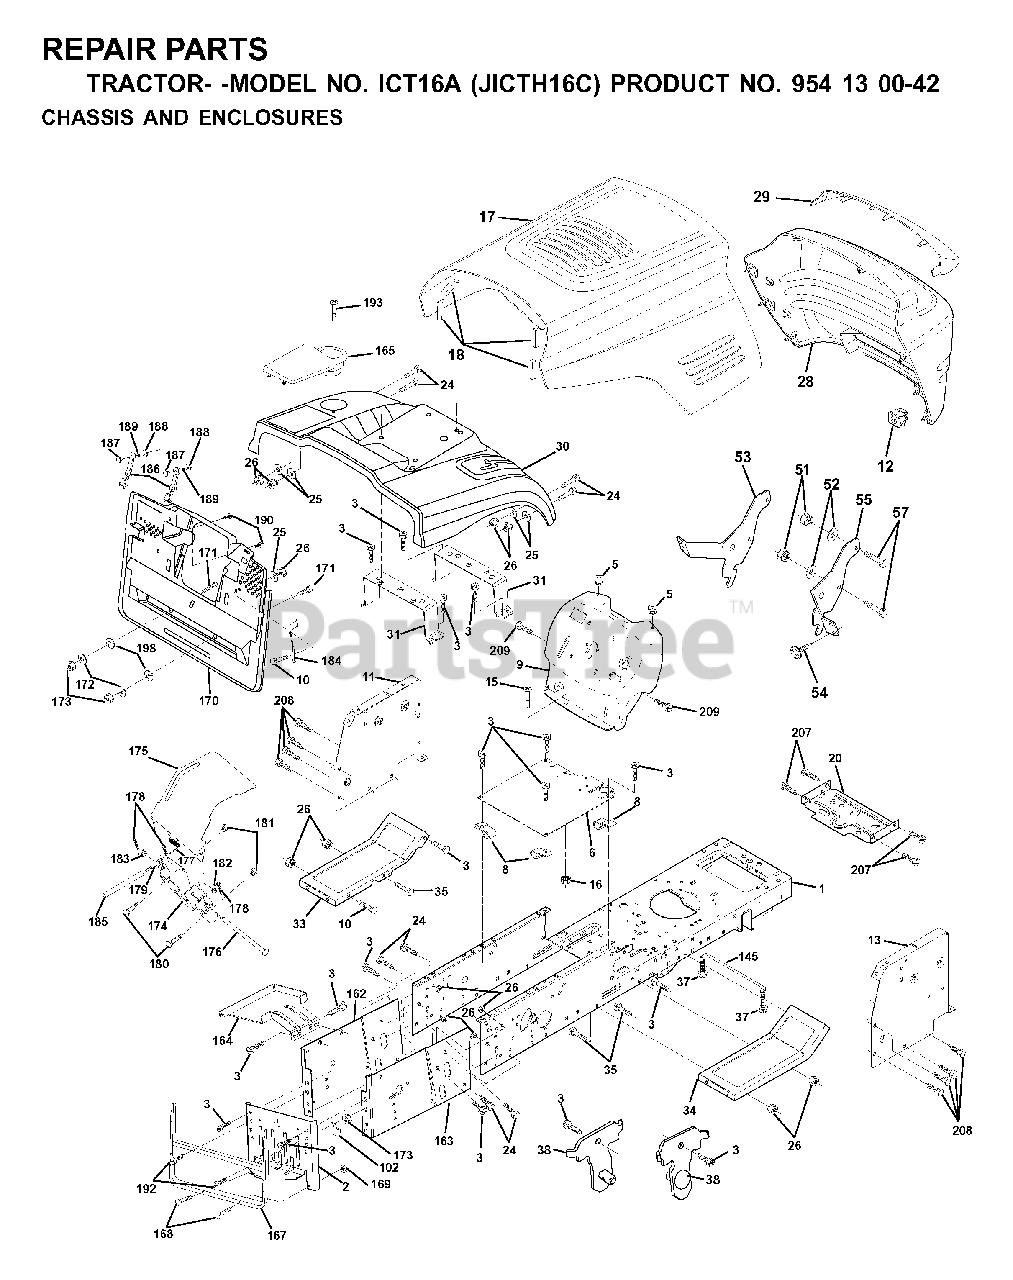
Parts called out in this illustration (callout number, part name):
1	CHASSIS STAMPING
3	SCREW 3/8-16X3/4
5	BUMPER.RUBBER.HOOD
6	SADDLE FLAT
8	CLIP,INSULATOR
10	BOLT D
11	PANEL DASH LH
13	PANEL DASH
16	NUT
18	BUMPER HOOD T
20	PLATE MTG
25	WASHER
26	NUT
31	BRACKET SUPPORT FENDER
38	BRACKET
51	LOCKNUT
57	BOLT
102	CLIP T
145	ROD PIVOT CHASSIS/HOOD
164	SUPPORT
168	BOLT.ROUND.HEAD.SQUARE.NECK
169	NUT T
170	COVER BACKPLATE
171	BOLT
172	WASHER
176	HINGE PIN
177	SPRING COVER LH
178	COTTER PIN
179	ROD PIVOT
180	BOLT RB
181	LOCKNUT
184	BRACKET
185	TUBE LEVER
186	LATCH ASSY
187	WELDNUT
189	LOCKWASHER
190	SCREW
192	SCREW LT
193	SCREW, TRUSS 1/4-20 X 3/4"
207	SCREW, 5/16-18 X 1/2
208	SCREW 3/8-16X1/2
209	SCREW, 3/8-16X3/4
210	SCREW
